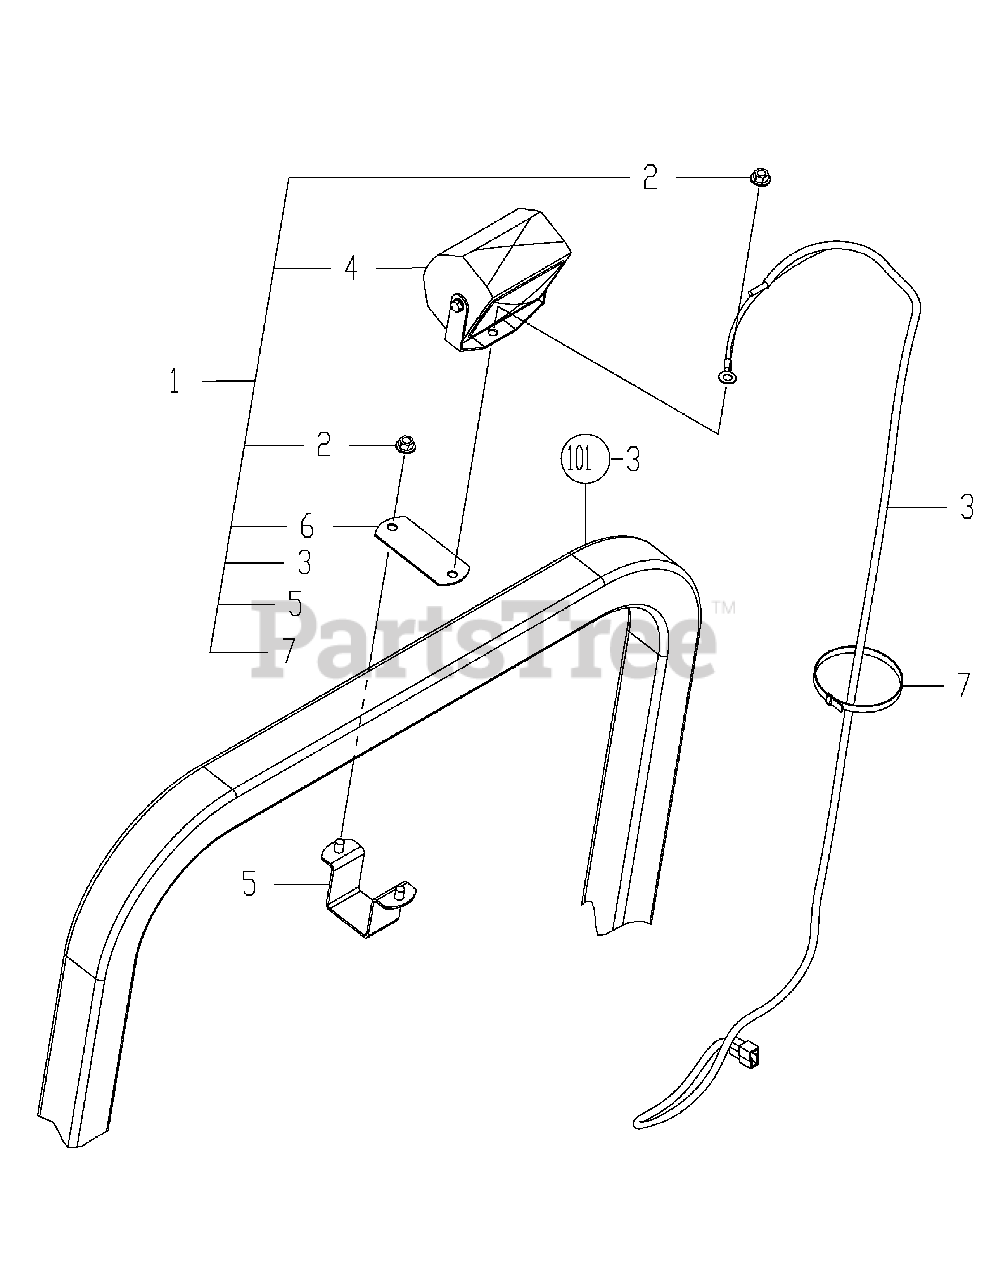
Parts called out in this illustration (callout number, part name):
1	LAMP KIT, WORK
3	CABLE, WORK ASSY
4	LAMP, WORK ASSY
5	STAY A, WORK LAMP
6	STAY B, WORK LAMP
